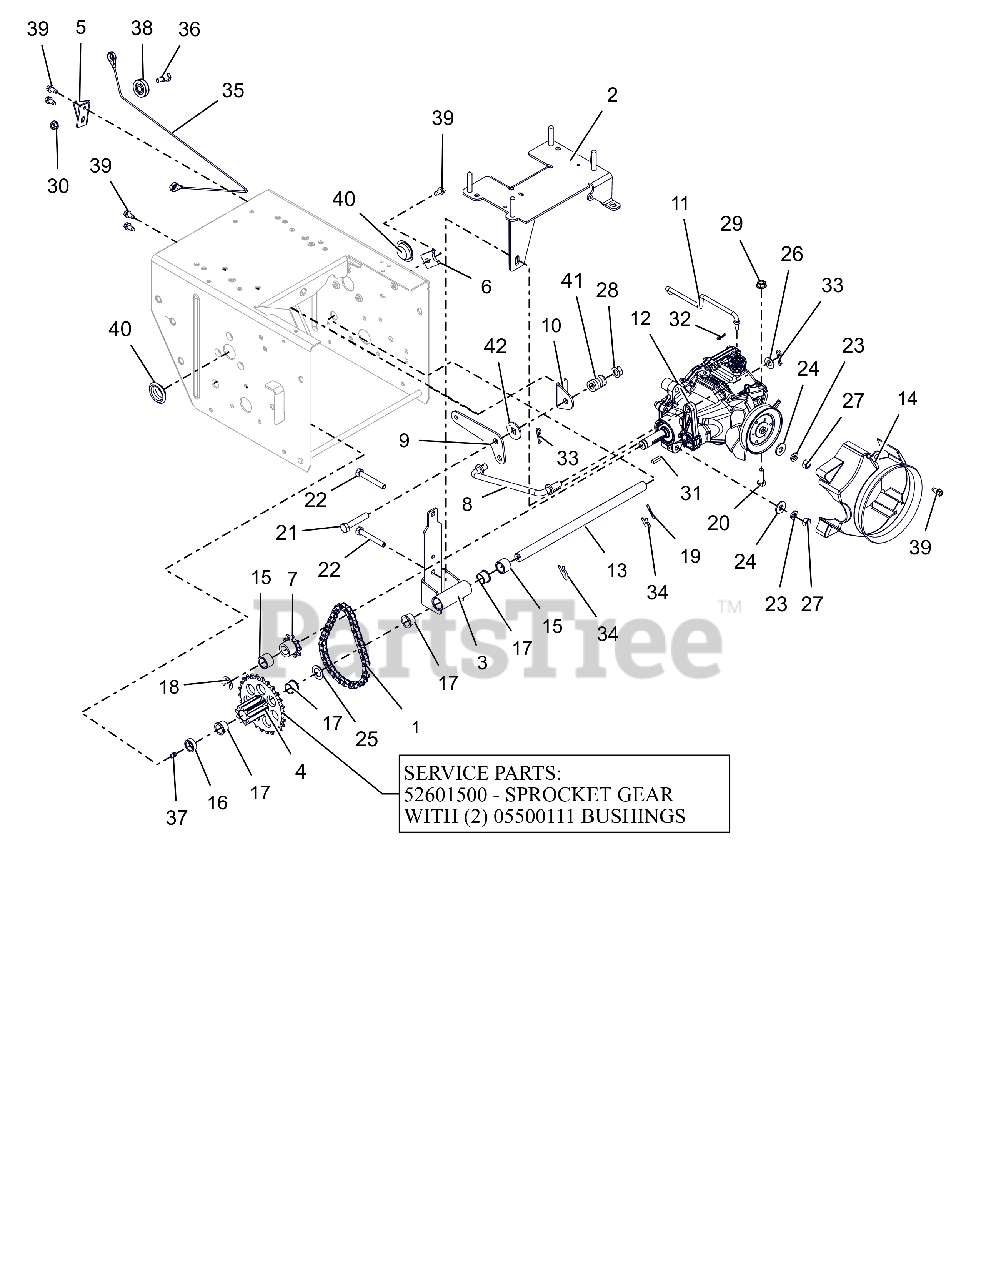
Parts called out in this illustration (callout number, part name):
1	CHAIN - #41, 32 PITCHES
2	BRACKET, HYDROSTATIC TRANS XLG
3	TRANS MOUNT, TENSIONING, WHEEL
4	PINION & SPROCKET
4	PINION & SPROCKET W/BUSHINGS
5	BRACKET, CABLE PULLEY
6	TAB, ANTI ROTATION
7	SPROCKET, PINION 9T W/KEY
8	ROD, HYDRO TRANS SHIFT
9	PIVOT, HYDRO TRANS SHIFT
10	BRACKET, HYDRO SHIFT PIVOT
11	ROD, HYDRO BYPASS
12	TRANSMISSION, HYDROSTATIC
13	SHAFT, PINION - HARDENED
14	SHROUD, HYDROGEAR RT-310
15	SPACER, .635X.880X.611
16	BSHG-SLV, .635X.880X.305
17	BSHG-FLG .625X.750X.500X.875
18	RG-RTNG-EXT .625X.042
19	@PIN-GRV .125X1.00 TP E ALLOY
20	@BLT-HEX .31-18X1.00 GR5 YWZC
21	@BLT-HEX .38-16X2.00 GR5 YWZC
22	@BLT-HEX .31-18X2.25 GR5 YWZC
23	WSHR-LK .312X.097 HVY YWZC
24	@WSHR-FL-STL.38X.875X.083 YWZC
25	WSHR-FL-STL .630X1.005X.062 YZ
26	@WSHR-FL-STL.406X.812X.065 YWZ
27	@NUT-HEX .31-18 YWZC
28	@NUT-LK-TOP-FLG .38-16 YWZC
29	@NUT-LK-TOP-FLG .31-18 YWZC
30	@NUT-LK-TOP-FLG .25-20 YWZC
31	KEY-SQ .188X.75X.188
32	PIN-HAIR INT .06X.18X.77
33	PIN-HAIR INT .08X.18X1.18 YWZC
34	PIN, SPRING CLIP
35	CABLE, TRACTION, HYDRO PRO
36	BOLT, SHLDR-.375X.375X.25-20
37	ZERK,FITTING .25X.125 DRIVE IN
38	PULLEY, CABLE
39	SCR-TAP .25-20X.50 HWH TR YWZ
40	PLUG, HOLE - 1.125"
41	SG-COMP .187X.56X1.62
42	FRICTION WASHER
